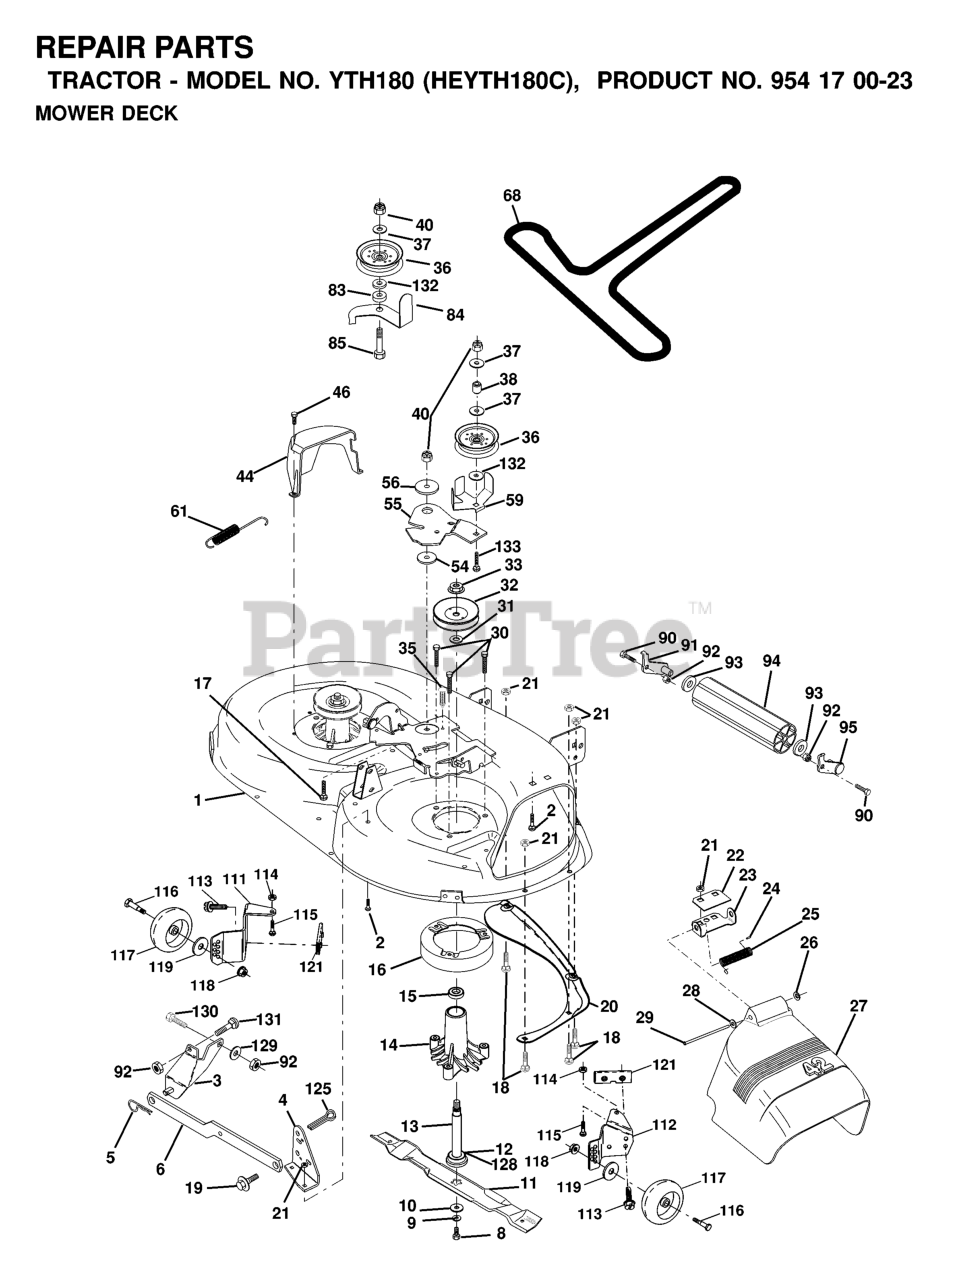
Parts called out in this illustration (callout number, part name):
1	DECK 42"
2	RP BOLT 5/16-18 X3/4 ZN/YEL GR
3	BRKT ASM SWAY BAR
4	BRKT DECK SW BAR
5	RETAINER-SPRNG RB
6	REAR SUSP ARM
8	BLADE BOLT
9	LOCKWASHER
10	WASHER.BLADE
11	BLADE 42", YTH 160
12	BEARING.BALL.#6204.(MANDREL)
13	SHAFT ASM VENT
14	HOUSING.MANDREL.VENTED (MACHD)
16	STRIPPER
17	BOLT CARRIAGE
18	BOLT
19	BOLT SHD 5/16-18
20	BAFFLE.VORTEX
21	LOCKNUT
22	STIFFENER BRACKET
23	DEFLECTOR BRACKET
24	CAP-SLEEVE LT
25	SPRING TORSION
26	NUT PUSH M
27	SHIELD DEFLECTOR
28	Washer 11/32 x 5/8 x 16 Ga SD
29	ROD.HINGE
30	SCREW THDROL ROLLING WASHER HD
31	WASHER
32	PULLEY/MANDREL
33	NUT
35	FASTENER.XMAS.TREE
36	FLAT IDLER PULLEY
37	WASHER
38	IDLER SPRING SPACER
44	GUARD MANDREL LH BLACK
46	SCREW.1/4-20X5/8
54	HARDENED WASHER
55	IDLER ARM
56	SPACER.RETAINER.MOWER
59	GUARD, BELT
61	SPRING EXTENSION
84	KEEPER.BELT.IDLER
90	BOLT
91	BRACKET LH (A)
92	NUT
93	Washer 1 17/32 X 7/8 X 16 Ga
94	NOSE ROLLER
95	BRACKET RH (B)
111	BRACKET WHEEL GAUGE LH 42" DK
112	BRACKET WHEEL GAUGE RH 42" DK
113	SCREW 5/16"
114	NUT
115	BOLT.CARR.5/16-18X1/2
116	BOLT M
117	WHEEL.GAUGE.STANDARD
118	LOCKNUT
119	WASHER.5/16.FLAT.STE.STD.
121	BRACKET.EXTRUDED.GAGE.WHEEL
125	Pin Cotter 1/4 x 1 Plated
128	WASHER FELT
129	WASHER
131	BOLT D
132	Washer 13/32 x 1-3/8 x 13 Ga.
